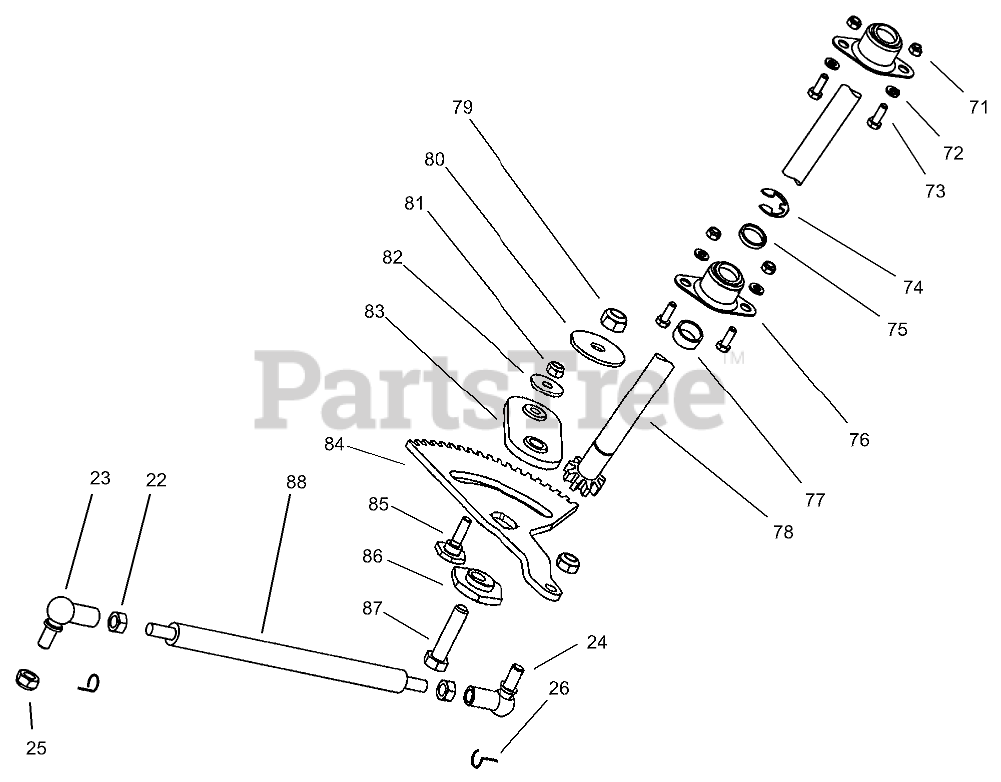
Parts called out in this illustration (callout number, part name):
22	NUT-HEX
23	Hsg-Ball Angle
24	STUD-BALL
25	NUT-SELF LOCKING
26	Stirrups-Locking
71	NUT-LOCK, NI
72	WASHER-PLAIN
73	SCREW-HH
74	CLIP-SPRING
75	SPACER-UPPER
76	BEARING-SPHERICAL
77	SPACER-LOWER
78	GEAR-STRG SHAFT PINION
78	Gear-Strg Shaft Pinion
79	NUT-LOCK
80	WASHER
81	NUT-LOCK, NI
82	WASHER-PLAIN
83	PLATE-STEERING
84	GEAR-SECTOR
85	BOLT-SHOULDER
86	ECCENTRIC
87	SCREW-HH
88	LINK-DRAG
